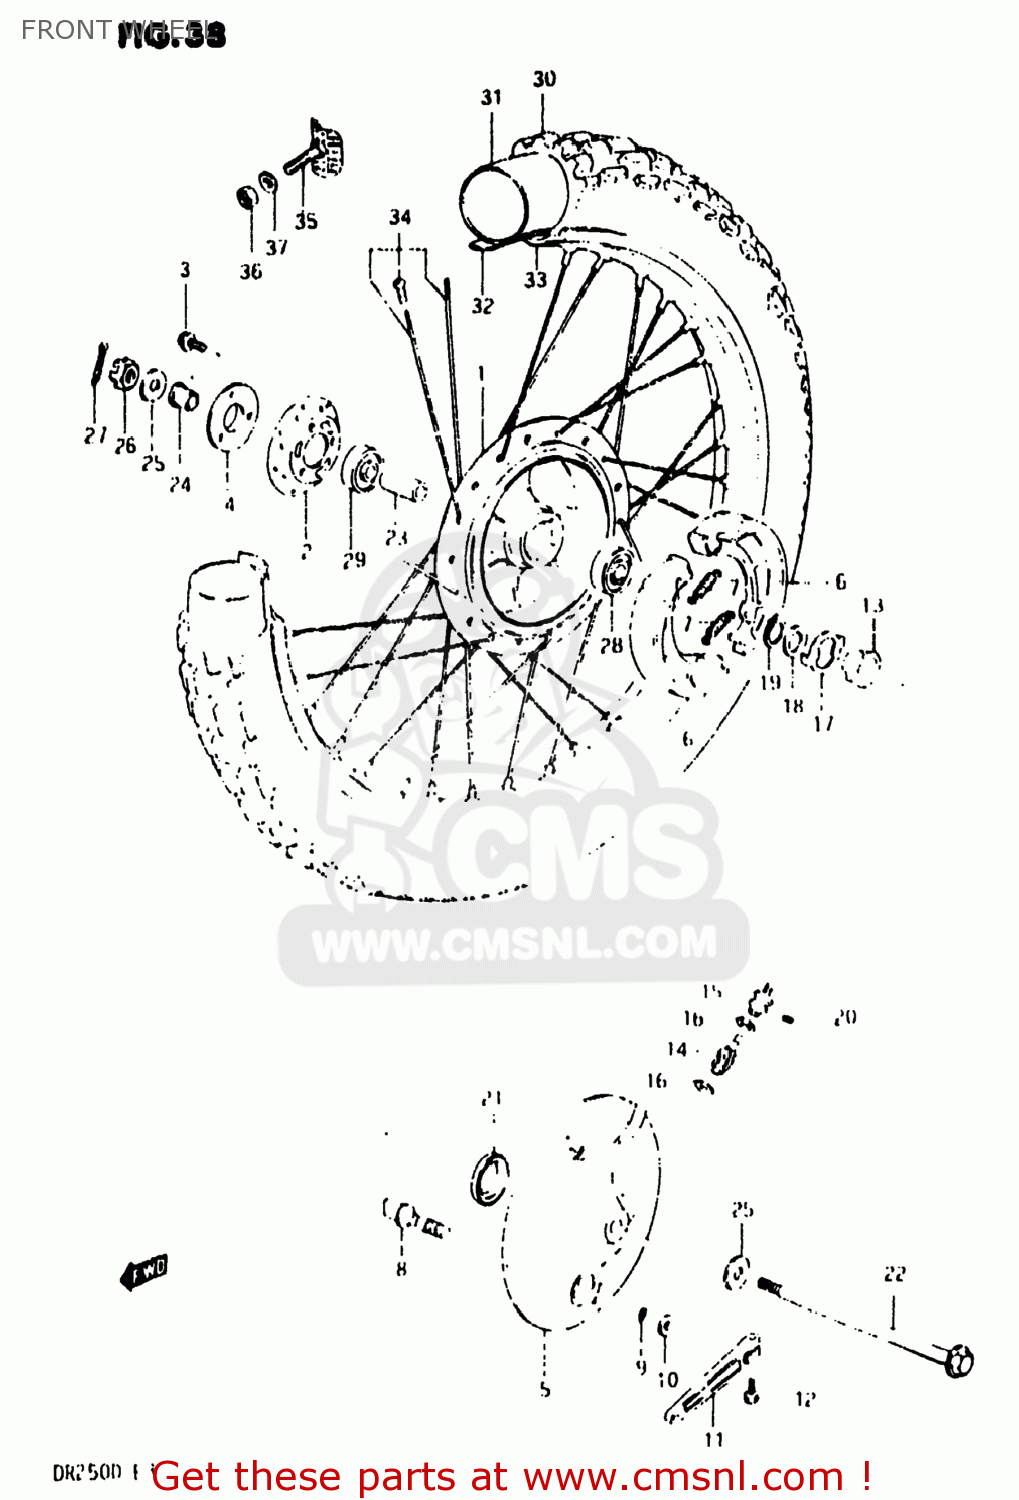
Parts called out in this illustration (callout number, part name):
1	HUB,FR WHEEL
2	FLANGE,FR HUB,R
3	BOLT
4	PLATE,FRONT HUB BEARING
5	PANEL,FRONT HUB
6	SHOE,BRAKE
7	SPRING(L:34)
8	CAM,FRONT BRAKE
9	O-RING (D:2.4 ID:13.8)
10	WASHER (14.5X22X1.6)
11	LEVER,FRONT BRAKE CAM
12	BOLT
13	GEAR,SPEEDOMETER
14	PINION,SPEEDOMETER
15	BUSH,METER GEAR OUTER
16	WASHER (5.1X9X0.4)
17	DRIVER,SPEEDOMETER GEAR
18	WASHER(18.5X24X1)
19	CIRCLIP
20	SCREW
21	OIL SEAL (43X58X7)
22	AXLE,FRONT
23	SPACER (12.6X19X52)
24	SPACER,FR AXLE,R
25	WASHER
26	NUT, REAR AXLE
27	COTTER PIN
28	BEARING
29	BEARING, RH
30	TIRE,FRONT
31	TUBE
32	PROTECTOR,WHEEL,INNER
33	RIM,FRONT WHEEL
34	SPOKE SET,FRONT
35	STOPPER,BEAD
36	NUT
37	WASHER
